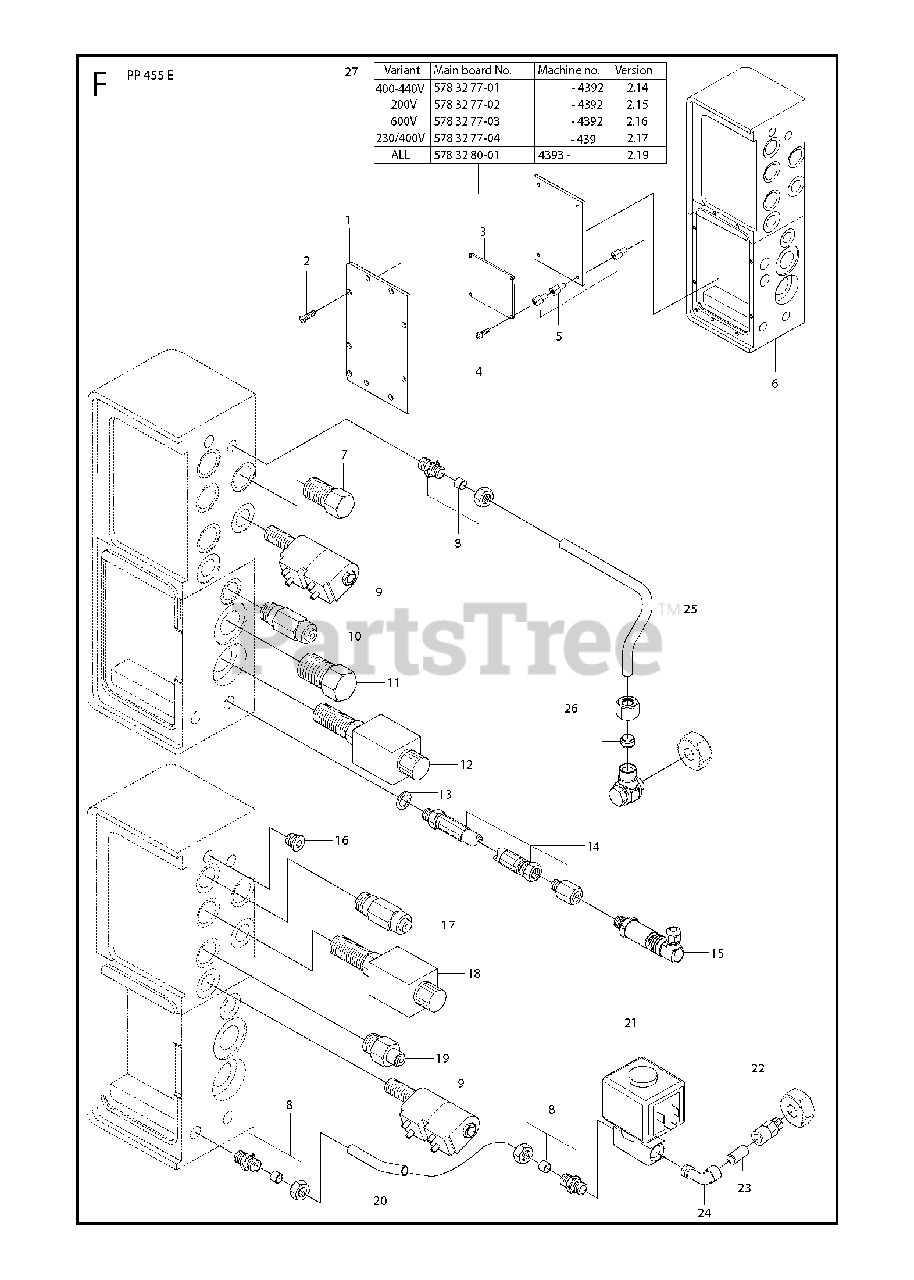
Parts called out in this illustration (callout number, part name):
13	SEALING WASHER
27	PRINTED CIRCUIT ASSYVariant 400-440V, Machine no - 4392, Version 2.14
27	PRINTED CIRCUIT ASSYVariant 200V, Machine no - 4392, Version 2.15
27	PRINTED CIRCUIT ASSYVariant 600V, Machine no - 4392, Version 2.16
27	PRINTED CIRCUIT ASSYVariant 230/400V, Machine no - 439, Version 2.17
27	PRINTED CIRCUIT ASSYVariant ALL, Machine no 4393 -, Version 2.19
